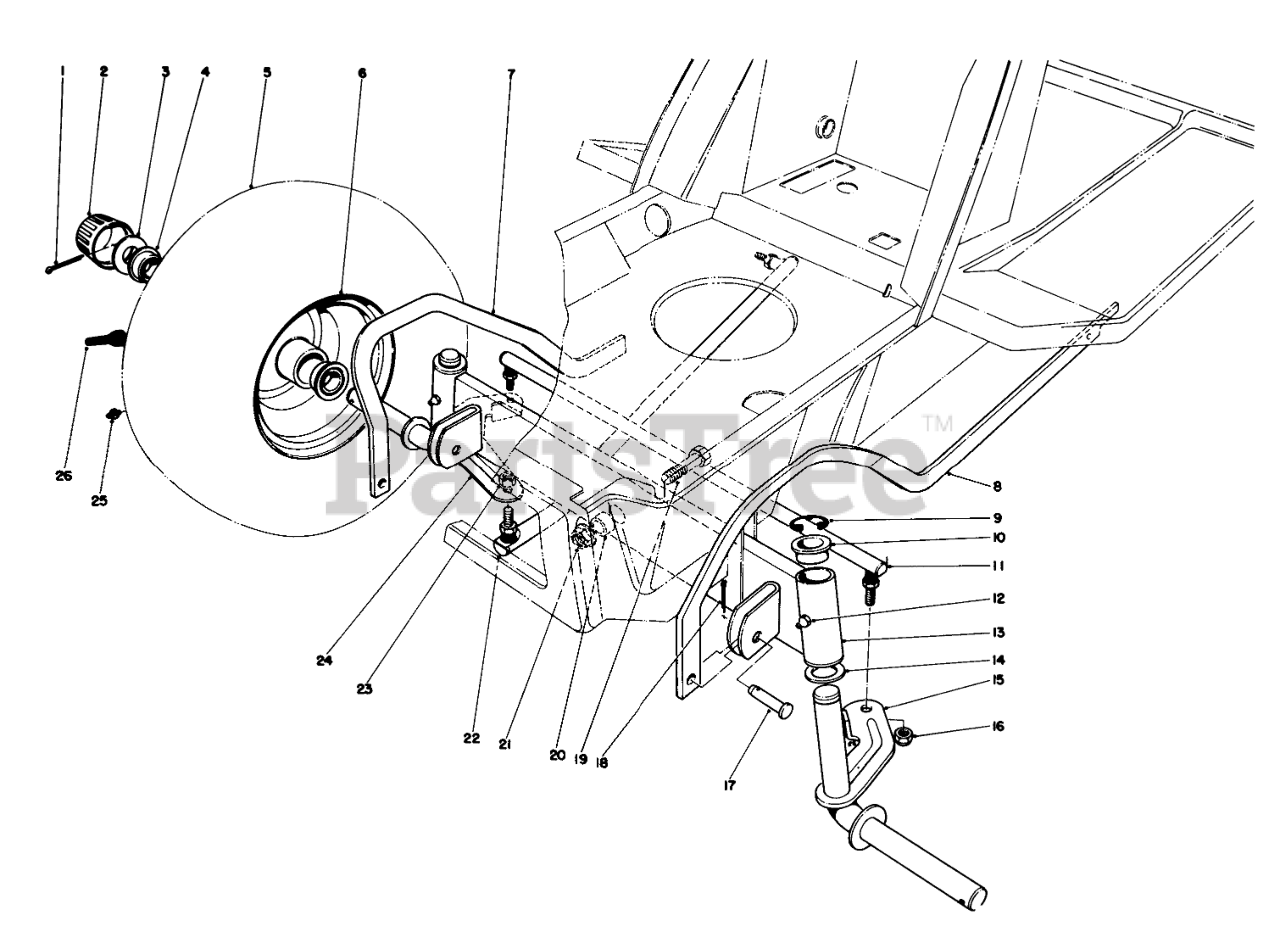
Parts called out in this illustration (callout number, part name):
1	PIN-COTTER
2	Cap-Hub
3	WASHER-PLAIN
4	Bearing
5	FRONT TIRE
6	FRONT RIM
7	Scissors Link-Front R.H.
8	Scissors Link-Front L.H.
9	E-RING
10	BEARING-FLANGE
11	Tie Rod Steering
12	Fitting-Grease
13	Front Axle (Incl. Ref. #10)
14	WASHER-THRUST
15	LH SPINDLE WA PP
16	NUT-LOCK NI
17	PIN-CLEVIS
18	PIN-COTTER
19	SCREW-HH
20	SPACER-AXLE, FRONT
21	NUT-HF
22	Steering Arm
23	Nut
24	RH SPINDLE WA PP
25	FITTING-GREASE
26	STEM-VALVE
